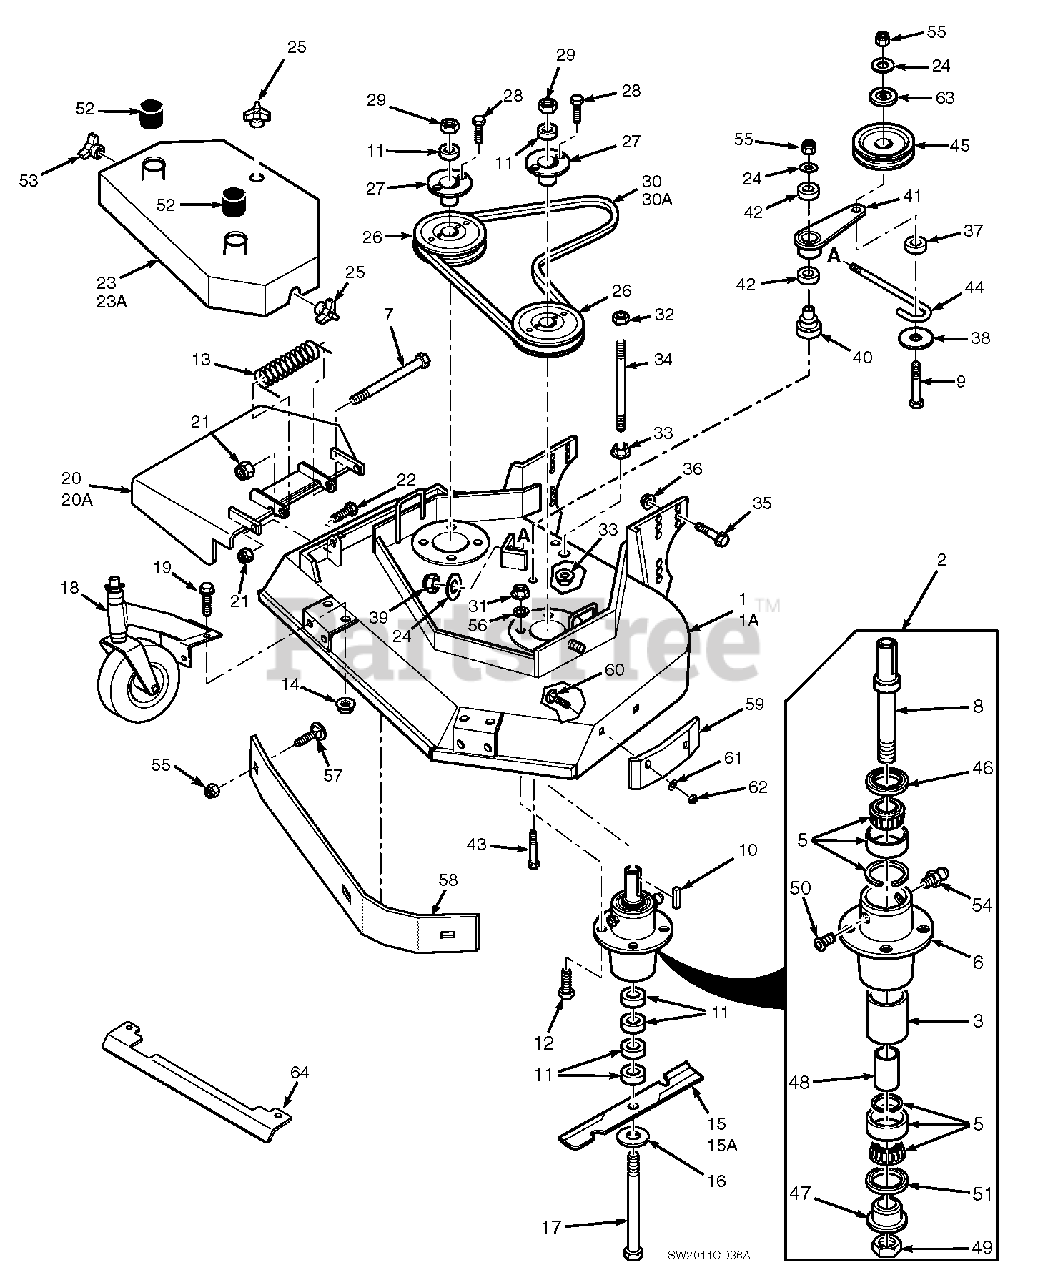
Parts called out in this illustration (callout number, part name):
1	Cutter Deck w/Decals
1A	Cutter Deck w/Decals
2	Cutter Spindle Assembly
3	Spacer, Outside
5	Bearing, Tapered
6	Spindle Housing
7	Bolt, 5/16-18 x 4-3/4"
8	Spindle Shaft
9	Bolt, 3/8-16 x 3-3/4" Hex Head
10	Key, 1/4 x 1/4 x 2"
11	Spacer, Cutter Blade - Small
12	Bolt, 5/16-18 x 1-1/2" Hex Head Grade 8
13	Spring, Chute Return
14	Nut 5/16-18 Serrated Flange
15	Cutter Blade, 16-1/2"
15	Cutter Blade, 18"
15A	Cutter Blade 16-1/2 Hi-Lift
15A	Cutter Blade, 18 Hi-Lift
16	Flatwasher, 5/8 W
17	Hex Hd. Bolt, 5/8-11 x 9-1/2"
18	Caster Assembly
19	Cpscrw,5/16-18 x 3/4" Ser.Flg. Hex Head
20	Discharge Chute
20A	Discharge Chute
21	Hex Nut, 5/16-18 Elastic Stop
22	Hex Hd Bolt, 5/16-18 x 1"
23	Belt Cover Assy
23A	Belt Cover Assy
24	Flat Washer, 3/8" Special
25	Wing Nut, 3/8-16
26	Pulley
27	Tapered Hub
28	Hex Hd. Bolt, 1/4-20 x 1"
29	Hex Nut, 5/8-11
30	Belt, Blade Drive
30A	Belt, Blade Drive
31	Elastic Stop Nut, 5/16-18 Grade 8
32	Hex Nut, 3/8-16 Center Locknut
33	Nut, 3/8-16 Serrated Flange
34	Support, Belt Cover
35	Cpscrw, 1/2-13 x 1"Ser.Flg. HH
36	Nut, 1/2-13 Spiralock
37	Spacer, J-Hook
38	Flatwasher, 3/8 x 1-1/2 x 16 GA
39	Elastic Stop Nut, 3/8-16
40	Idler Pivot
41	Idler Arm Assy.
42	Bearing
43	Cpscrw, 3/8-16 x 3-1/4" Hex Head
44	J-Hook
45	Idler Pulley, Belt Clutch
46	Seal, Cutter Spindle
47	Spindle Bushing
48	Spacer, Inside
49	Nut,1.06-18
50	Relief Fitting, Cutter Spindle
51	Seal, Cutter Spindle
52	Spindle Shield
53	Wing Nut, 3/8-16 (Small) RH side
54	Grease Fitting
55	Nut, Hex Elastic Stop 3/8-16
56	Lock Washer, 5/16"
57	Bolt, Carriage 3/8-16 x 1"
58	Baffle Weldment
59	Pad, Deck Wear
60	Bolt, Carriage 5/16-18 x 3/4"
61	Flatwasher, 5/16"
62	Hex Nut, 5/16-18 Center Locknut
63	Dust Shield
64	Heatshield
